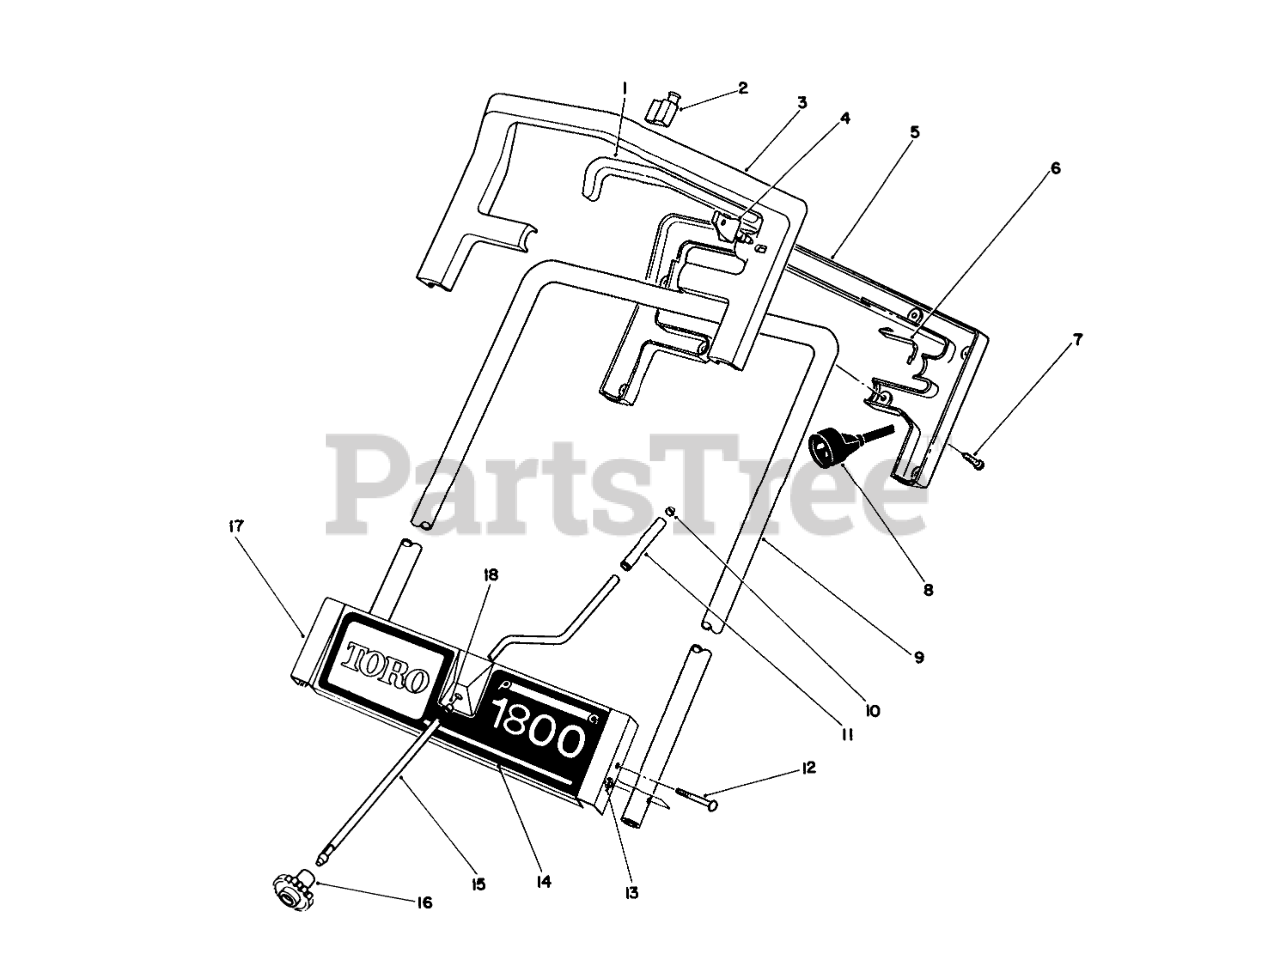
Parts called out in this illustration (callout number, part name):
1	Bar-Switch
1	Chute-Deflector
2	SWITCH
2	WASHER-FLAT
3	UPPER CONTROL HANDLE
3	NUT-LOCK, NI
4	KEY - 1800
4	Handle-Middle
5	1800 L CNTRL HANDLE
5	Screw
6	SPRING, INTERLOCK
6	WASHER-RUBBER
7	Screw
7	Chute-Lower
8	Cord-Supply
8	SCREW-CARR
9	TUBE-UPPER HANDLE
10	PUSHNUT-CAP, WASHER
11	Sleeve-Crank, Chute
12	Screw-HH
13	NUT-LOCK, NI
14	DECAL - ESCUTCHEON
15	Rod-Crank, Chute
16	Gear-Crank, Chute
17	Plate-Escutcheon
18	Bushing-Nyliner
